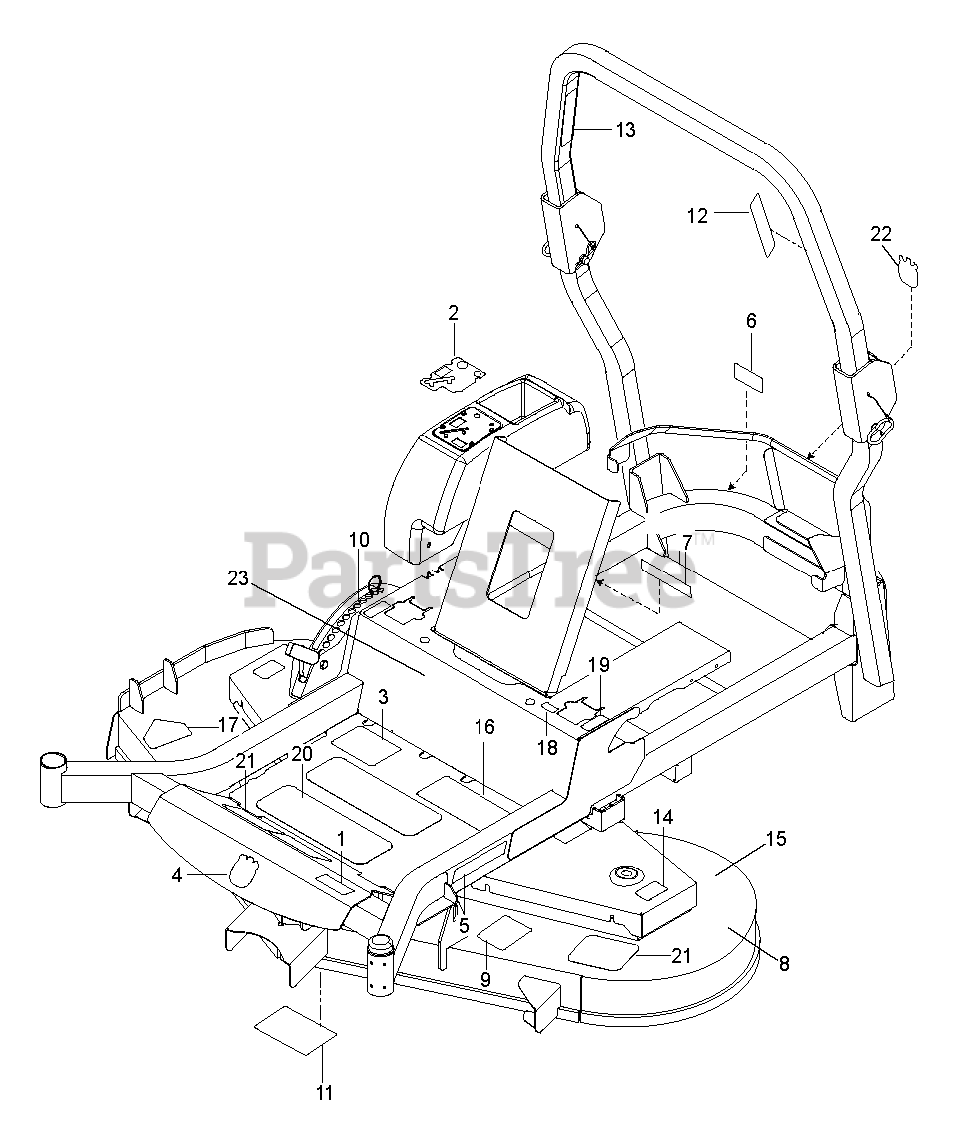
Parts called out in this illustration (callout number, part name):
1	DECAL ZTR MODEL NUMBER DECAL.Z
2	DECAL, CONSOLE HUS
3	DECAL.ZTR.STRTNGINST.REMOTECHK
4	DECAL.AUGER.HUSQ.CROWN.SNOW
5	RP.DECAL.BADGE.170MM.TEXTLOGO
6	DECAL, BELT DRIVE
7	EURO DECAL-BATTERY WARNIN6
8	DECAL.54DECK.CLEARCUT.VER2.18
9	DECAL BELT ROUTING DECAL DECAL
10	DECAL, HEIGHT ADJUST
11	DECAL, SERVICE
12	DECAL, ROPS, WARNING
13	DECAL ROPS
14	DECAL.DECK.CLEARCUT.NOSTEP
15	DECAL DECK DECAL DECAL.DECK.WA
16	DECAL ZTR WARNING DECAL DECAL.
17	DECAL.TRACT/ZTR.DECKWARN.HUSQ
18	DECAL.STR.S.T.SYSMBOLONLY.2014
19	DECAL.ZTR.MOTCONTRL.SYMBOL.HUS
20	ANTI-SKID PAD
22	DECAL, CROWN H, 110MM
23	DECAL ZTR BRAND GRAPHIC DECAL.
